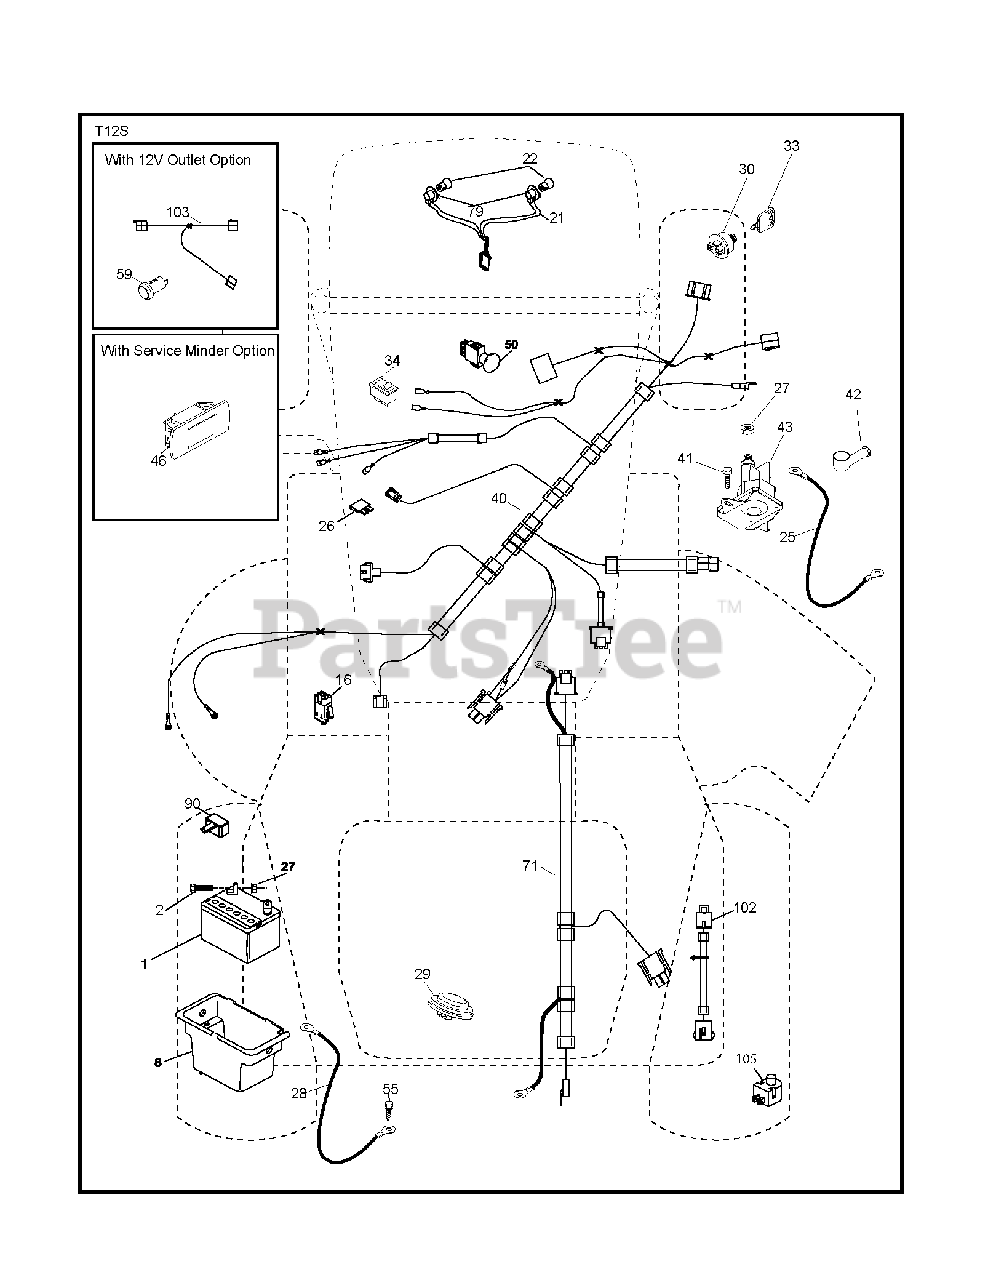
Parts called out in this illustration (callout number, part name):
1	Battery, Dry 30 Amp
2	BOLT.HEX.1/4.X.3/4.DICHROMATE
8	BOX.BATTERY.MNT.REAR.L
16	SWITCH INTERLOOK PUSH-IN
21	HARNESS.LIGHT W/4152J BULBS
25	CABLE.STARTER.6GA.BL/RED.14.
26	FUSE 20AMP
27	NUT
28	CABLE.BLACK.18"REAR.BA
29	SWITCH.SEAT.DELTA.OPC.
30	SWITCH.IGN.DELTA.W.LGH.ROS
33	KEY.CHAIN.BLISTER.PACK.GEN.USA
40	HARNESS.IGN.DASH.HUQ/P
41	SCREW
42	TERMINAL COVER
43	SOLENOID.W/BRASS.PLUNGER
46	RP GUAGE.SRVCMNDR.HRMTR.
50	RB PTO.SWITCH.8 TERMINAL.BLACK
55	SCREW 5/16"
71	HARNESS.IGN.CHASS.TEX.REAR.BAT
79	BULB HOLDER ASM.
90	COVER.TERMINAL.BATTERY
102	HARNESS PIGTAIL PCH TEX ROS
105	REVERSE SWITCH
